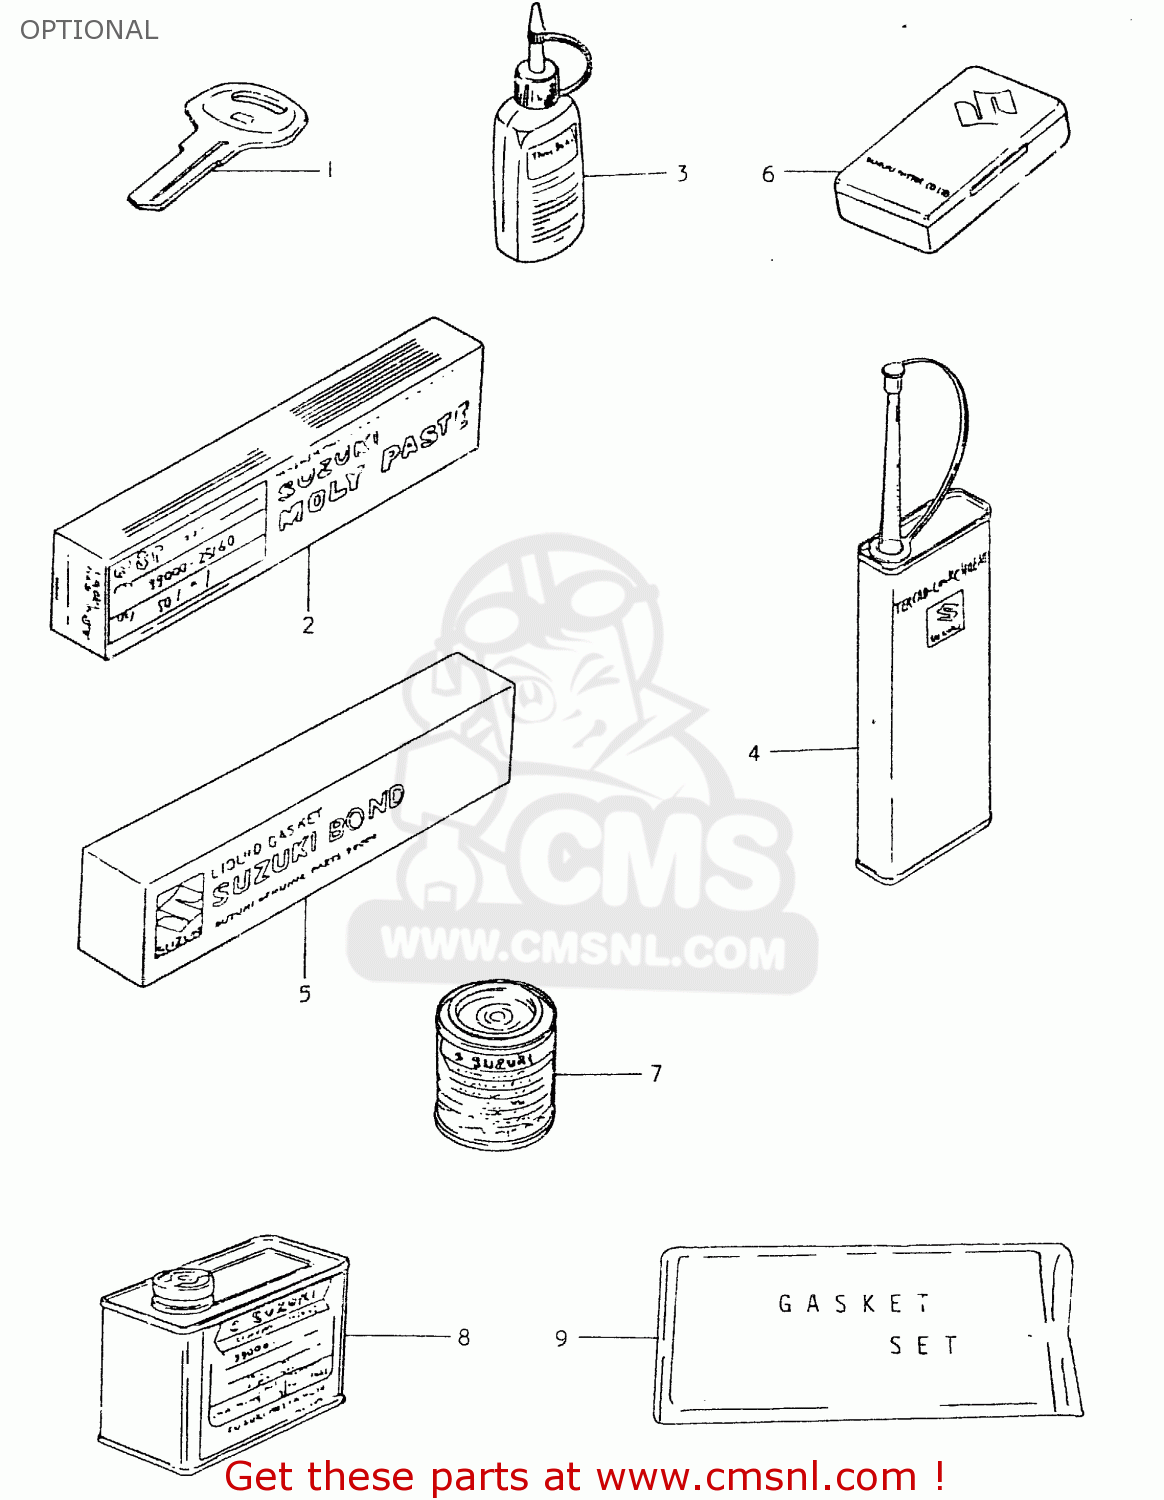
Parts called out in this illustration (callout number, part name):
1	KEY,BLANK
2	SUZUKI MOLY PASTE
3	THREAD LOCK SUPER (1332B)
4	THREAD LOCK NO.1401 CLEAR 200G
5	LIQUID GASKET 1215 250G GREY
6	TUBE REPARING TOOL
7	PAINT,BLACK
8	PAINT (BLACK)
9	GASKET SET
